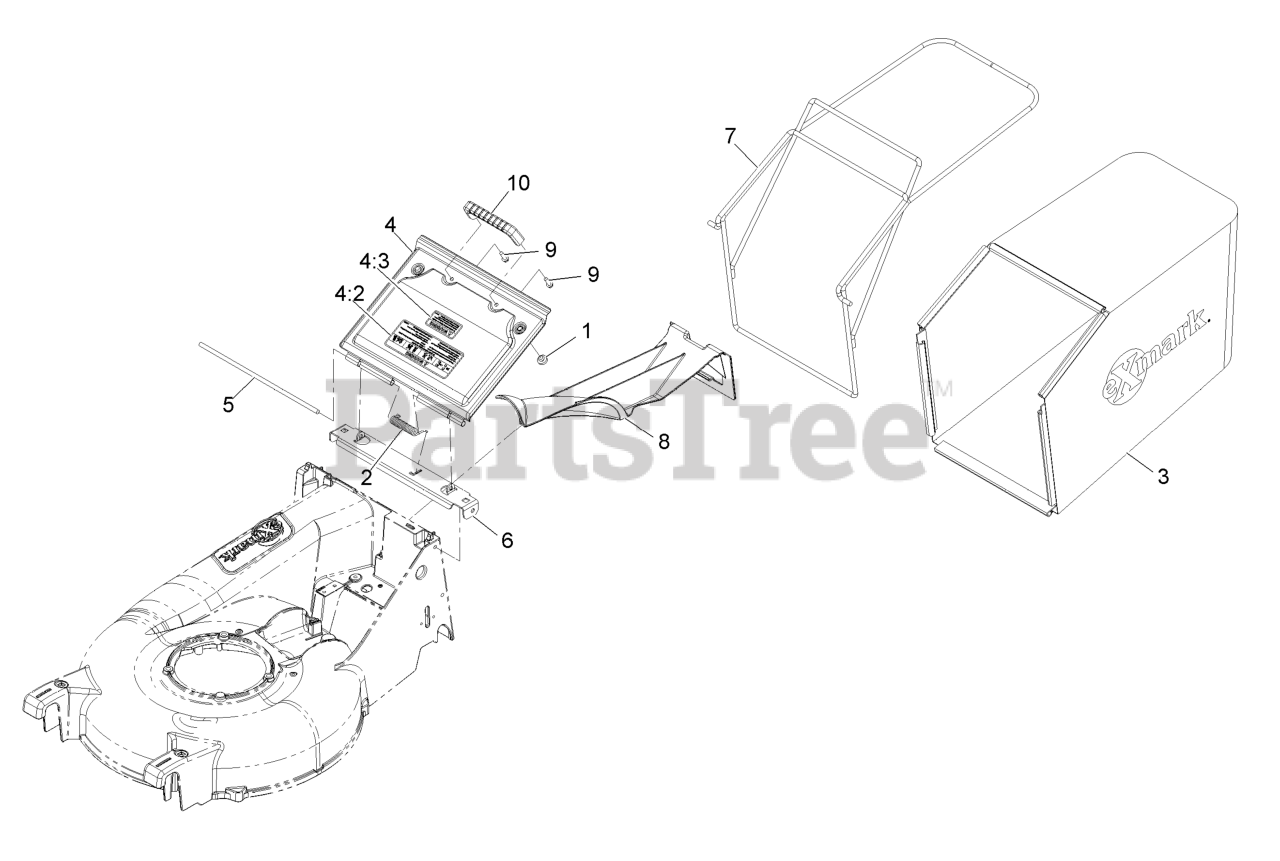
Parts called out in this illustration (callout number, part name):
2	SPRING-TORSION,COVER
3	BAG,GRASS P21
4	DOOR W/DECAL
4:2	DECAL-WARNING
4:3	DECAL-WARNING DOOR SM
5	ROD,DOOR PIVOT
6	BRACKET-DOOR P21
7	WLD,BAG FRAME
8	PLUG,MULCH
9	SCREW-HWH
10	HANDLE-DOOR
